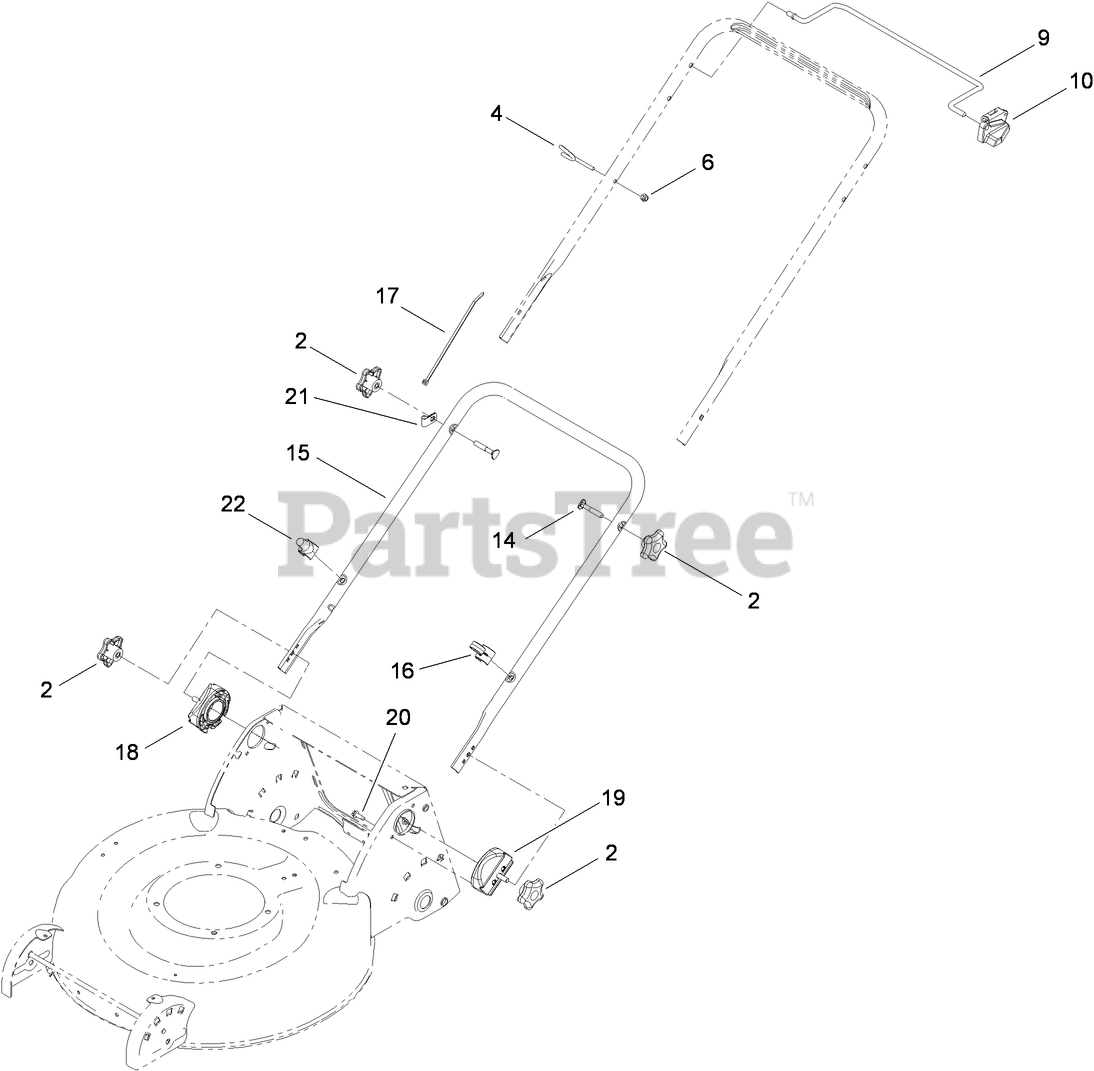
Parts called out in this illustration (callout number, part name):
2	KNOB-HANDLE
4	GUIDE-ROPE
6	NUT-LOCK, NI
9	Bail-Control
10	Stop-Pivot
14	SCREW-HANDLE
15	HANDLE-LOWER
16	GUIDE-CABLE
17	TIE-CABLE
18	RH HANDLE MOUNT ASM
19	LH HANDLE MOUNT ASM
20	SCREW-HWHTF
21	CLAMP-R
22	GUIDE-ROPE, LOWER
